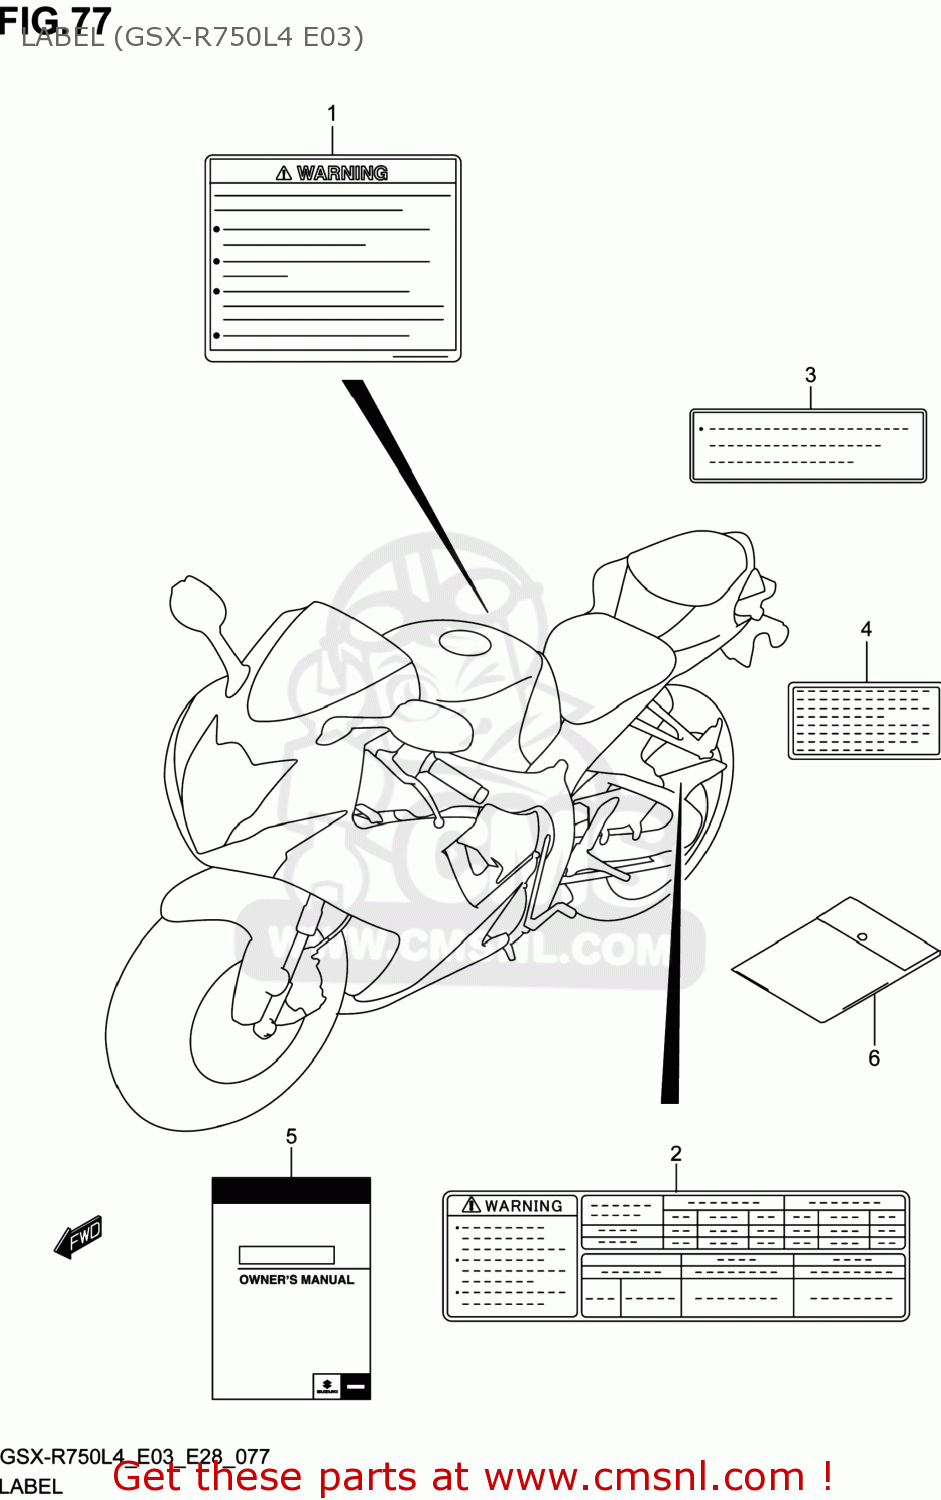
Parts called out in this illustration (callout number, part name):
1	LABEL,GENERAL WARNING
2	LABEL,TIRE INFORMATION
3	LABEL,FUEL INFORMATION
4	LABEL,MANUAL NOTICE
5	MANUAL,OWNER'S
6	BAG,OWNER'S MANUAL
